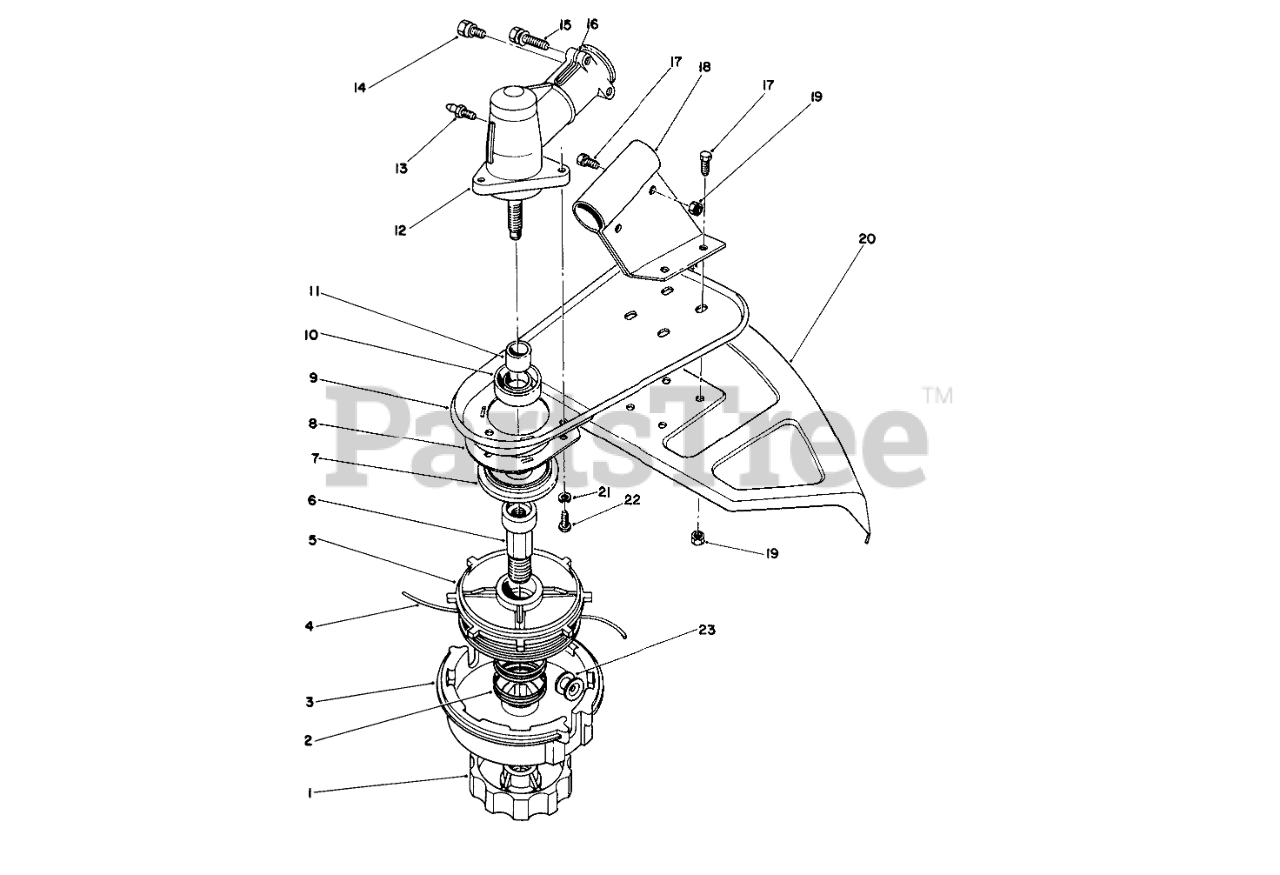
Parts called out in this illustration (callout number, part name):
1	LH KNOB(SERVICE ONLY)
2	SPRING (SERVICE)
3	SPOOL HSG (SERVICE ONLY
5	INNER SPOOL(SERV ONLY)
6	SHAFT (SERVICE ONLY)
7	DUST CAP F/W
8	GRASS WRAP GUARD
9	SHIELD SUPPORT R
10	OIL SEAL
11	SPLINED SLEEVE
12	Gear Box Assembly (Incl. Ref. #10, 11, & 13-16)
14	HHMS SCREW
15	HHMS SCREW
16	WASHER
17	SCREW-SHH
18	Bracket-Shield
19	NUT-LOCK, NI
20	GRASS SHIELD-STEEL
21	LOCKWASHER
22	SCREW
23	EYELET(SERVICE)
